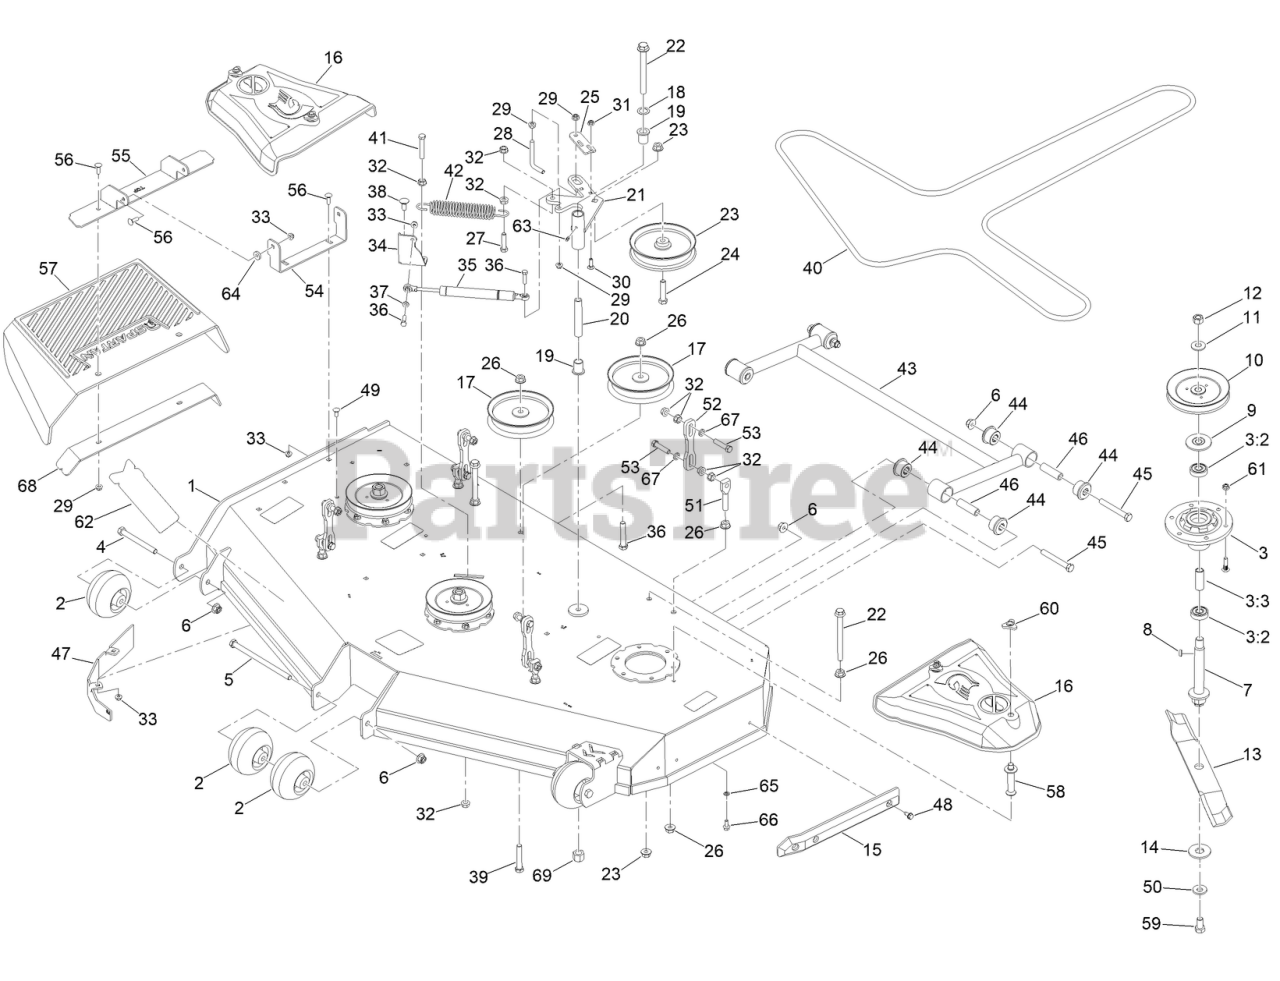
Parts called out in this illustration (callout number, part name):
1	ASM-DECK W/ DECALS
2	MWR ANTI-SCALP WHL W/O GREASE FITTING
3	SPINDLE ASM 6" DECK
3:2	BEARING-BALL
3:3	SPACER, BEARING
4	SCREW-HH
5	1/2-13 X 8-1/2 HEX C/S GR 2 ZINC YELLOW
6	NUT-LOCK
7	SHAFT - SPINDLE
8	6MM X 6MM X 20MM ROUNDED MACHINE KEY
9	GUARD,BEARING TOP .989
10	PULLEY
11	M20 SPRING WASHER (44.5MMOD/ 3.3MM THK)
12	M20X1.5 C8.8 HEX NUT
13	BLADE-ROTARY
14	WASHER-HEX
15	MWR NYLON DECK GUARD
16	COVER-BELT
17	6-3/4IN IDLER PULLEY 15/16IN SPACER ASSY
18	.767IDX1.125ODX.016 THK TRIP WV WASHER
19	3/4IN ID X15/16IN OD X 1-1/8IN FLNG BUSH
20	MWR INNER IDLER SPACER
21	MWR DECK IDLER PULLEY ARM ASSY BLACK
22	1/2-13 X 5-1/2 HEX FLANGE BOLT GR 8 ZY
23	6-3/4IN IDLER PULLEY 7/16IN SPACER ASM
24	SCREW-HH
25	DECK IDLER PULLEY BELT RETAINER BRKT
26	NUT-HHF
27	SCREW-HH
28	BOLT-L
29	3/8-16 HEX FLANGE NUT W/SERR ZINC YELLOW
30	BOLT-CARR
32	NUT-HF
33	NUT-HF, NI
34	DECK BELT IDLER DAMPER MTG BRKT BLACK
35	IDLER GAS SPRING
36	SCREW-HH
37	.312IDX.625ODX.062 THK THRUST BRG OI BRZ
38	SCREW-CARR
39	1/2-13 X 2-3/4 HEX FLANGE BOLT (GR.8) YZ
40	61 DECK BELT
42	MWR DECK SPRING
43	54IN/61IN DECK FRAME STABILIZER BLACK
44	RED A80 SUSP BUSHING
45	1/2-13 X 3-3/4 HEX C/S (GR.5) ZC/YEL
46	UTV A-ARM BUSHING SLEEVE
47	BAFFLE-WIPER 61 PAINTED BLACK
48	SCREW-HWH, THREAD CUT
49	BOLT-CARR
50	M16 SPRING WASHER (39MMOD/ 3.9MM THK)
51	MWR DECK HEIGHT ADJUSTMENT STUD
52	MWR DECK SUSP LINK BLACK
53	SCREW-HH
54	MWR CHUTE MTG BRKT BLACK
55	RT/SRT DECK CHUTE HINGE ASSY BLACK
56	5/16-18 X 1 CARRIAGE BOLT GR 8 YZ
57	2020 RT/SRT RUBBER DISCHARGE CHUTE
58	PIN-BELT COVER
59	M16X1.5-30MM C10.9 HEX BOLT
60	NUT-KNOB
62	2022 KGZ 61IN DECK DECAL
63	1/4IN DRIVE TYPE GREASE FITTING YZ
64	.312 ID X .875OD X .1875 THK F/W NYL
65	WASHER-LOCK
66	SCREW-HHF
67	.443 ID X .749 OD X .125 THK NYLON BLACK
68	DECK CHUTE HINGE BACKER BRKT BLACK
69	NUT-LOCK, NI
